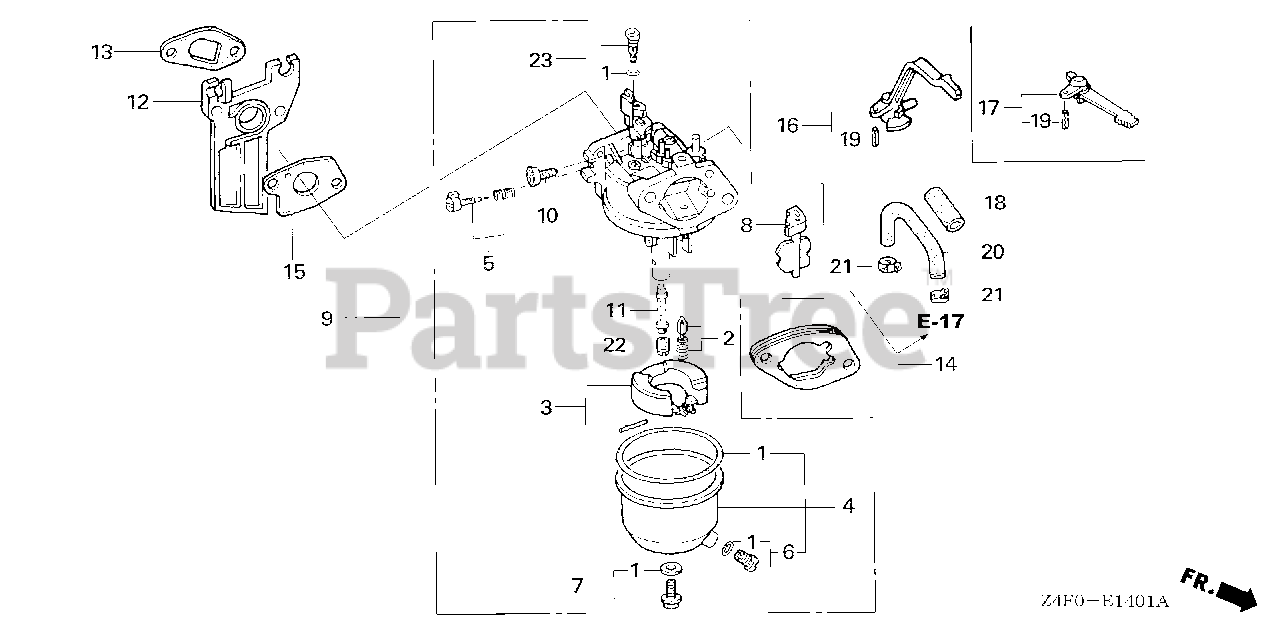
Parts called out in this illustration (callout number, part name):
1	GASKET SET
2	VALVE SET, FLOAT (SEAT NOT INCLUDED)
4	CHAMBER SET, FLOAT
5	SCREW SET, PILOT
6	SCREW SET, DRAIN
7	SCREW SET
9	CARBURETOR ASSY. (BE62C A)
10	SCREW, THROTTLE STOP
11	NOZZLE, MAIN
12	INSULATOR, CARBURETOR
13	GASKET, INSULATOR
14	SPACER, CARBURETOR
15	GASKET, CARBURETOR
17	LEVER, CHOKE (STD)
19	PIN, SPRING (2X12)
22	JET, MAIN (#58)
22	JET, MAIN (#60)
22	JET, MAIN (#62)
23	JET SET, PILOT (#35)
